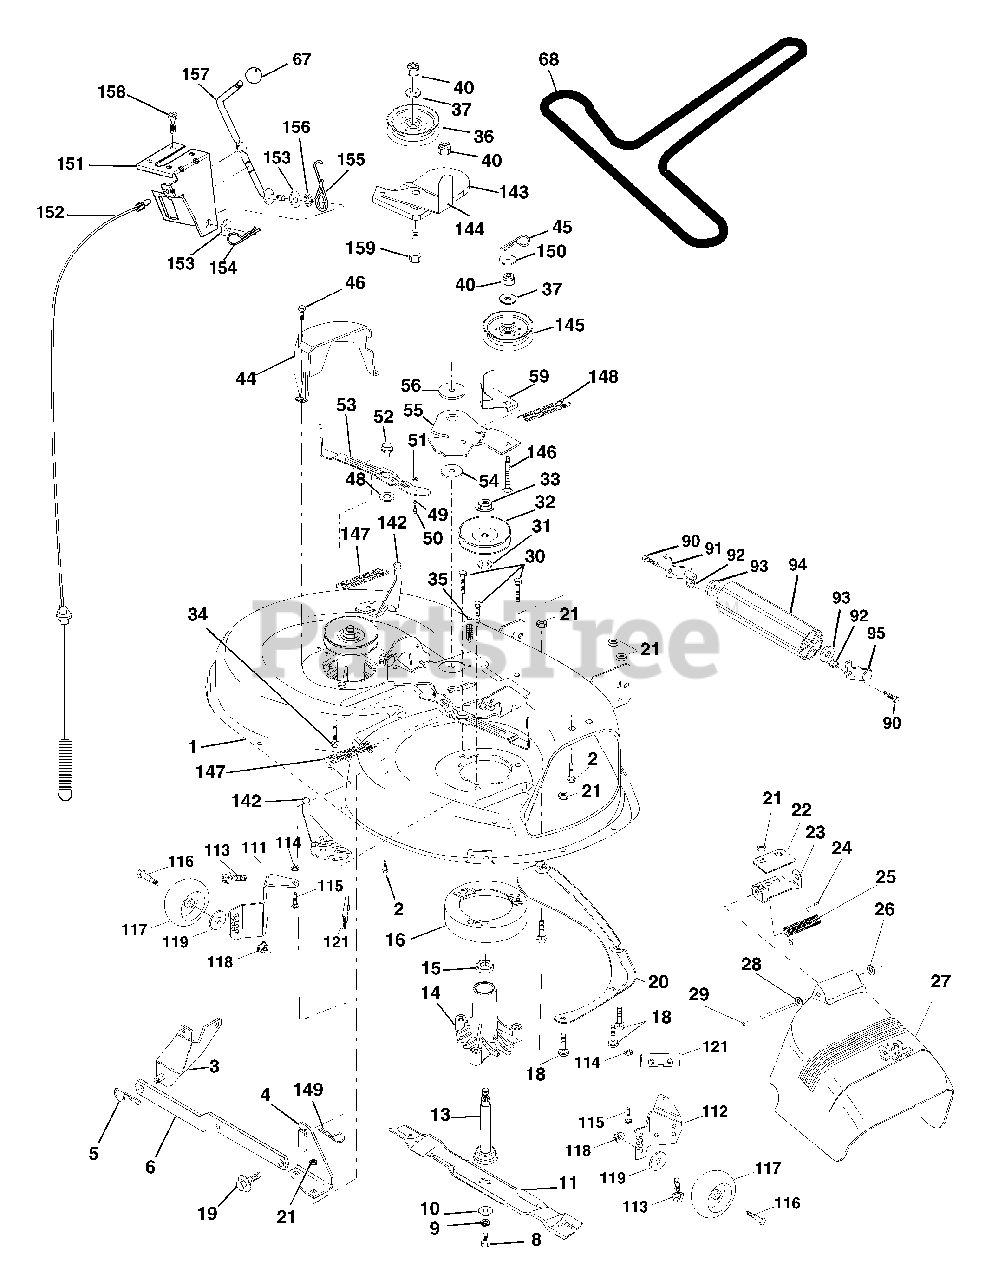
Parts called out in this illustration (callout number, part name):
1	Deck Asm MWR 42" weldment
2	Bolt Rdhd Sqnk 5/16-18unc X3/4
3	Bracket Asm Fr Sway Bar 38/42
4	Bracket Asm Deck 42" sway Bar
5	Retainer Spring
6	Arm Suspension Rear
8	Bolt 3/8 - 24 X 1.25 Gr 8
9	Washer Lock Hvy 3/8
10	Washer Hard Blade Mower Vented
11	Blade Mower 42"
13	Shaft Asm W/lower Bearing
14	Housing Mandrel Vented
15	Bearing Ball Mandrel
16	Stripper Mower Vented
18	Bolt Rdhd Sqnk 5/16-18 X 5/8
19	Bolt Shoulder
20	Baffle Vortex 42
21	Nut Crownlock 5/16-18 UNC
22	Stiffener Bracket 42" deck
23	Bracket Deflector Mower 42"
24	Cap Sleeve 80x 112 Blk Mower
25	Spring Torsion Deflector 2 52
26	Nut Push Phos & Oil
27	Shield Deflector Mower 42" Blk
28	Washer 11/32 X 5/8 X 16 Ga
29	Rod Hinge 42" 6 75 Wlg
30	Screw Thd Rolling Washer Head
31	Washer Spacer Mower Vented
32	Pulley Mandrel 42"
33	Nut 9/16 Toplock Flng Oil Dip
34	Bolt Rdhd 3/8-16uncx1-3/4 Gr5
35	Fastner Christmas Tree
36	Pulley Idler Flat 3 060
37	Washer 13/32 X 13/16 X 16
40	Nut Crownlock 3/8-16 UNC
44	Guard Mandrel LH Black
45	Spring Retainer 1" Zinc/cad
46	Screw Hex Thd Cut 1/4-20x5/8 T
48	Washer Hardened Smaller
49	Roller Asm Cam Follower
50	Bolt Shldr 10-24 Zinc Gr 5 42"
51	Nut Lock #10-24 Unc
52	Bolt Shoulder 5/16-18 Unc Blkz
53	Arm Asm Pad Brake
54	Washer Hardened
55	Arm Idler 42" mower LT/YT
56	Spacer Retainer Mower
59	Guard TUV Idler
67	Knob Rd 3/8-16 Plstc Thds Blk
68	V-Belt Mower 42"
90	Bolt Fin Hex 3/8-16 UNC x 1
91	Bracket Asm Noseroller LH
92	Nut Lock Hex W/Ins 3/8-16 Unc
93	Washer 17/32 x 7/8 x 16 Ga.
94	Roller Nose 38 & 42
95	Bracket Asm Noseroller RH
111	Bracket Wheel Gauge LH 42" Deck
112	Bracket Gauge Wheel RH 42" Deck
113	Screw 5/16-18
114	Nut Keps 5/16-18 UNC
115	Bolt Carriage 5/16-UNC x 1/2
116	Bolt Shoulder
117	Wheel Gauge
118	Nut Centerlock 3/8-16 UNC
119	Washer 3/8 x 7/8 x 14 Ga.
121	Bracket Extruded Guage Wheel
129	Washer 13/32 x 13/16 x 12 Ga.
130	Bolt Fin Hex 3/8-16 UNC x 1 Gr. 5
131	Bolt Rdhd Sqnk 3/8-16 x 1
142	Arm Spring Brake Mower
143	Bracket Arm Idler 42"
144	Keeper Belt 42" Clutch Idler
145	Pulley Idler Flat
146	Bolt Carriage Idler
147	Spring Extension
148	Spring Return Idler
149	Retainer Spring Yellow
150	Washer 9/32 x 3/4 x 16 Ga.
151	Bracket Clutch Cable
152	Clutch Cable 42"
153	Washer Flat 3/8" Type B
154	Spring Retainer
155	Spring Retention Lvr Cltch Cab
156	Spacer Clutch Cable
157	Rod Clutch Cable 3/8"
158	Screw Hex Thd Cut 1/4-20 x 5/8
159	Bolt Rdhd Sqn 3/8-16 Unc x 1-3/4
